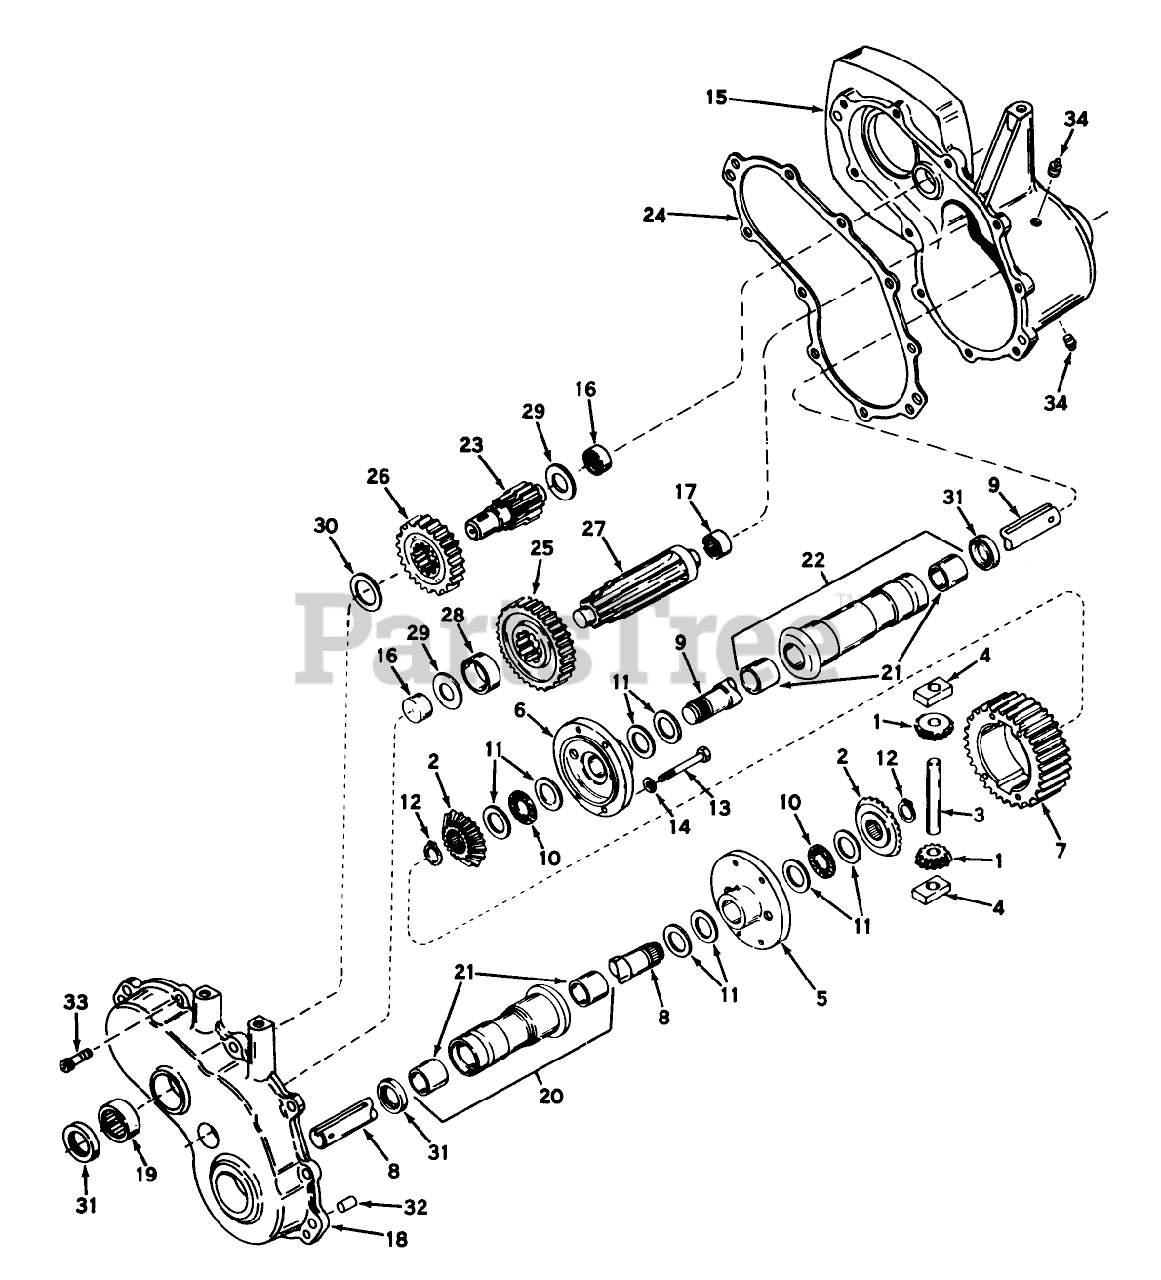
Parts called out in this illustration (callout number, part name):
1	Pinion-Bevel
2	Gear-Bevel
3	Pin-Drive
4	Biock-Drive
5	Carrier, Differential
6	Carrier, Differential
7	Gear, Ring
8	Axle, L.H.
9	Axle, R.H.
10	Bearing-Thrust
11	Washer
12	Ring-Snap
13	Screw-Hex Hd.
14	Lockwasher
15	Case Assy. (Incl. Nos. 16 17)
16	Bearing
17	Bearing-Needle
18	Cover Assy. (Incl. Nos. 16 19)
19	Bearing Needle
20	Housing Bushing Assy., L.H. (Incl. No. 21)
21	Bushing
22	Housing Bushing Assy., R.H. (Incl. No. 21)
23	Shaft, Brake
24	Gasket
25	Gear-Output
26	Gear-Spur
27	Shaft, Output
28	Spacer
29	Washer
30	Washer
31	Seal-Oil
32	Dowel Pin
33	Screw, Hex hd. self tapping
